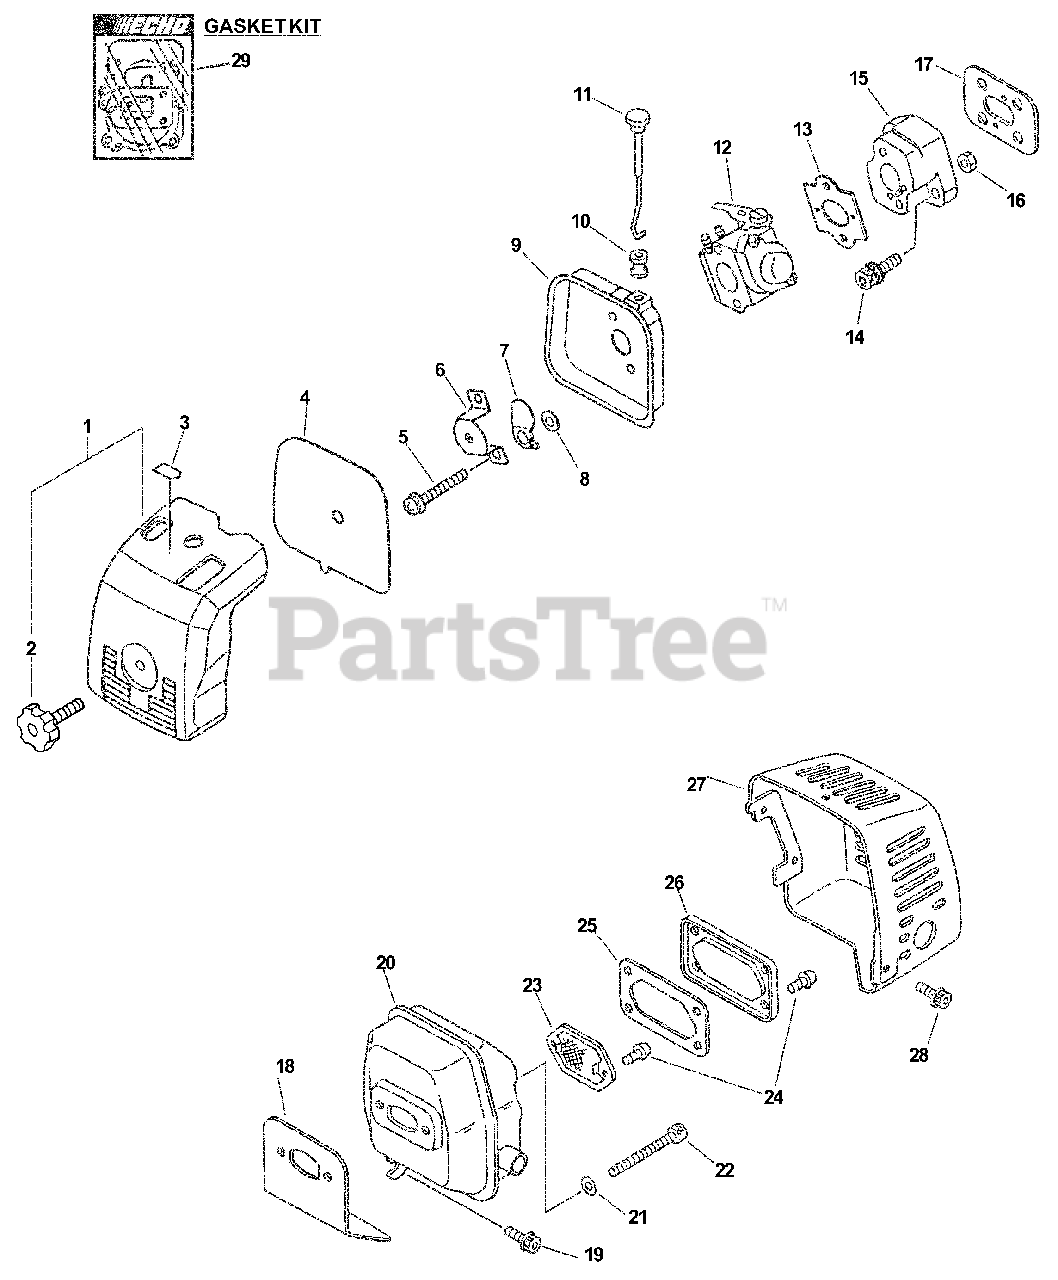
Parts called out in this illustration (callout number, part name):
1	AIR FILTER COVER ASSY
2	THUMBSCREW
3	LABEL, CHOKE
4	FILTER, HEAVY-DUTY AIR
5	BOLT 5×57
6	PLATE, PREVENT
7	SHUTTER, CHOKE
8	WASHER 5.2×8×0.8T
9	CASE, AIR FILTER
10	GROMMET, CHOKE
11	ROD, CHOKE
12	CARBURETOR
13	GASKET, CARBURETOR
14	BOLT 5×25
15	INSULATOR, INTAKE
16	NUT M5
17	GASKET, INTAKE
18	GASKET, MUFFLER
19	BOLT 5×12
20	MUFFLER
21	WASHER, FLAT 5.5×10×0.8
22	BOLT 5×60
24	SCREW 4×10
25	GASKET, EXHAUST
26	LID, MUFFLER
27	COVER, MUFFLER
28	BOLT 5×14
29	GASKET KIT
